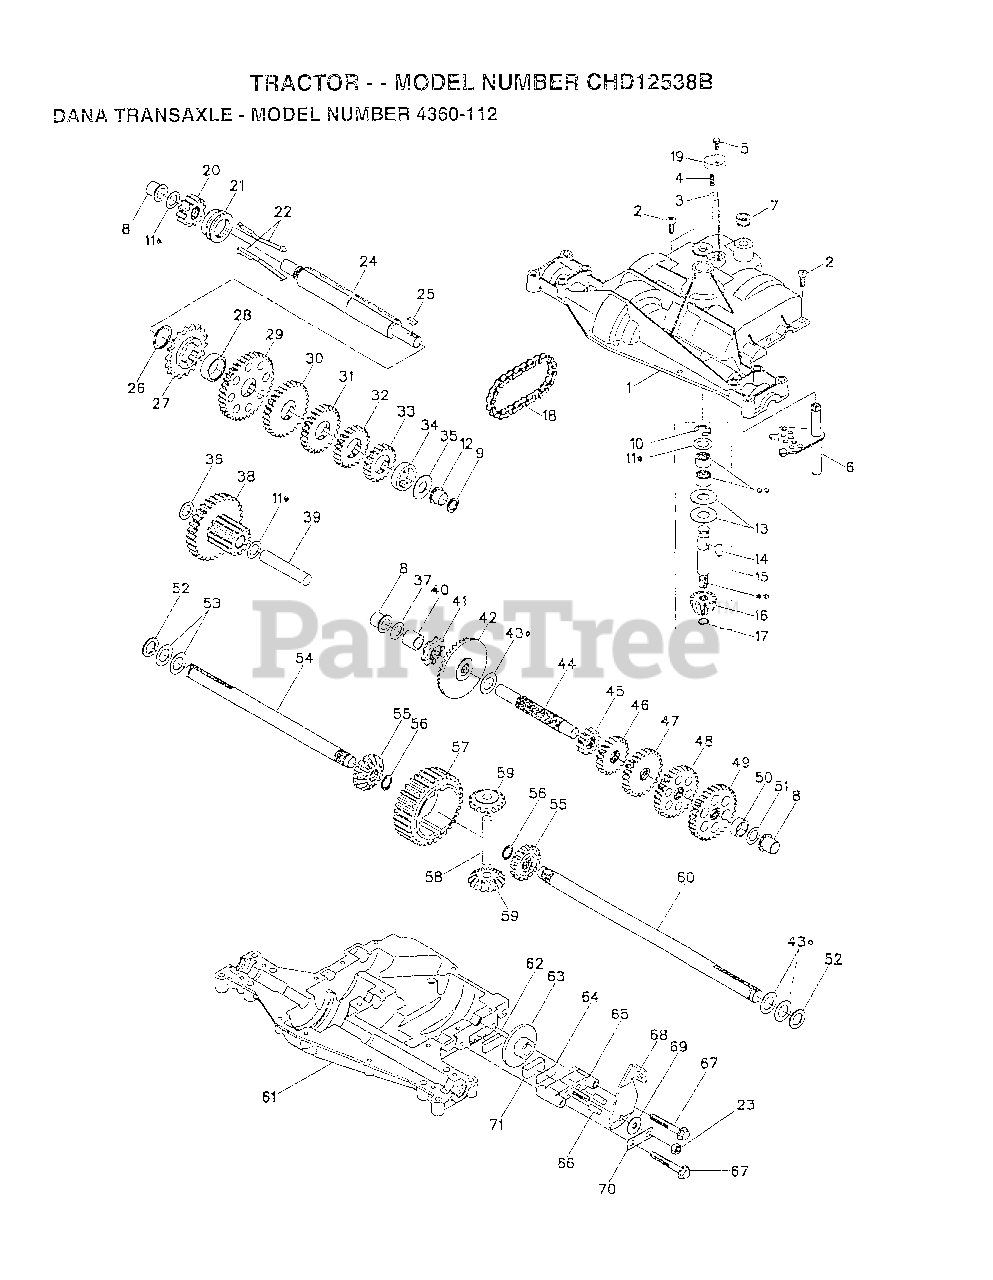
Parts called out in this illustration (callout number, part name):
1	HOUSING.UPPER.DANA.(5305J)
4	"SPRING, DETENT LT"
5	SCREW.TAPPING.1/4-20X.734
6	KIT SHIFTER ASM
9	SEAL.OIL.DAN.5508
10	RETAINING RING LT
11	ASM KIT SHIM 4689
12	BEARING.FLNG.5511
13	WASHER T
14	KEY WOODRUFF-DANA
15	AS KIT INPUT SHFT
16	PINION 14T T
17	"RING,RETAINING LT"
18	"CHAIN,24 PTCH LT"
19	COVER.DETENT.(5584)
20	GEAR.SPUR.12T.(5627)
21	CLUTCH.COL.5467
22	ASM KIT CLTCH KEY
23	NUT.LOCK.5/16-24
24	SHAFT INTERM DANA
25	WOODRUFF KEY
26	"RING,RETAINING LT"
27	SPROCKET 18T T
28	SPACER YT
29	GEAR SPUR 37 TTH
30	GEAR SPUR 30T
31	GEAR 25T LT
32	GEAR SPUR 22 TT
33	SPUR GEAR 19T
34	SPACER
35	"WASHER, PLAIN LT"
36	WASHER 045
37	WASHER 031
38	ASSY.GEAR.6153 12T&30T
39	SHAFT IDLER
40	SPACER T
41	SPROCKET 9T LT
43	ASM KIT SHIM
44	SHAFT T
45	GEAR SPUR 12 TTH
46	GEAR SPUR 20T
47	"GEAR, SPUR 25T LT"
48	GEAR 28T T
49	"GEAR, SPUR 31T LT"
51	WASHER 060
52	NEOPRENE WASHER
53	WASHER 031
54	AXLE.LH(5528-1)
55	GEAR 15T T
56	RING.RETAINING.(5270)
58	SHAFT T
59	GEAR 1ST T
60	AXLE.RH.(5528-2) DANA
61	HOUSING LOWER TNS
62	PUCK T
63	BRAKE DISC. T
64	SPACER LT
66	PIN T
67	SCREW.(5562) .5/16-18X2.35
69	WASHER LT
70	BRACKET, ANTI-ROTATION
71	PUCK T
